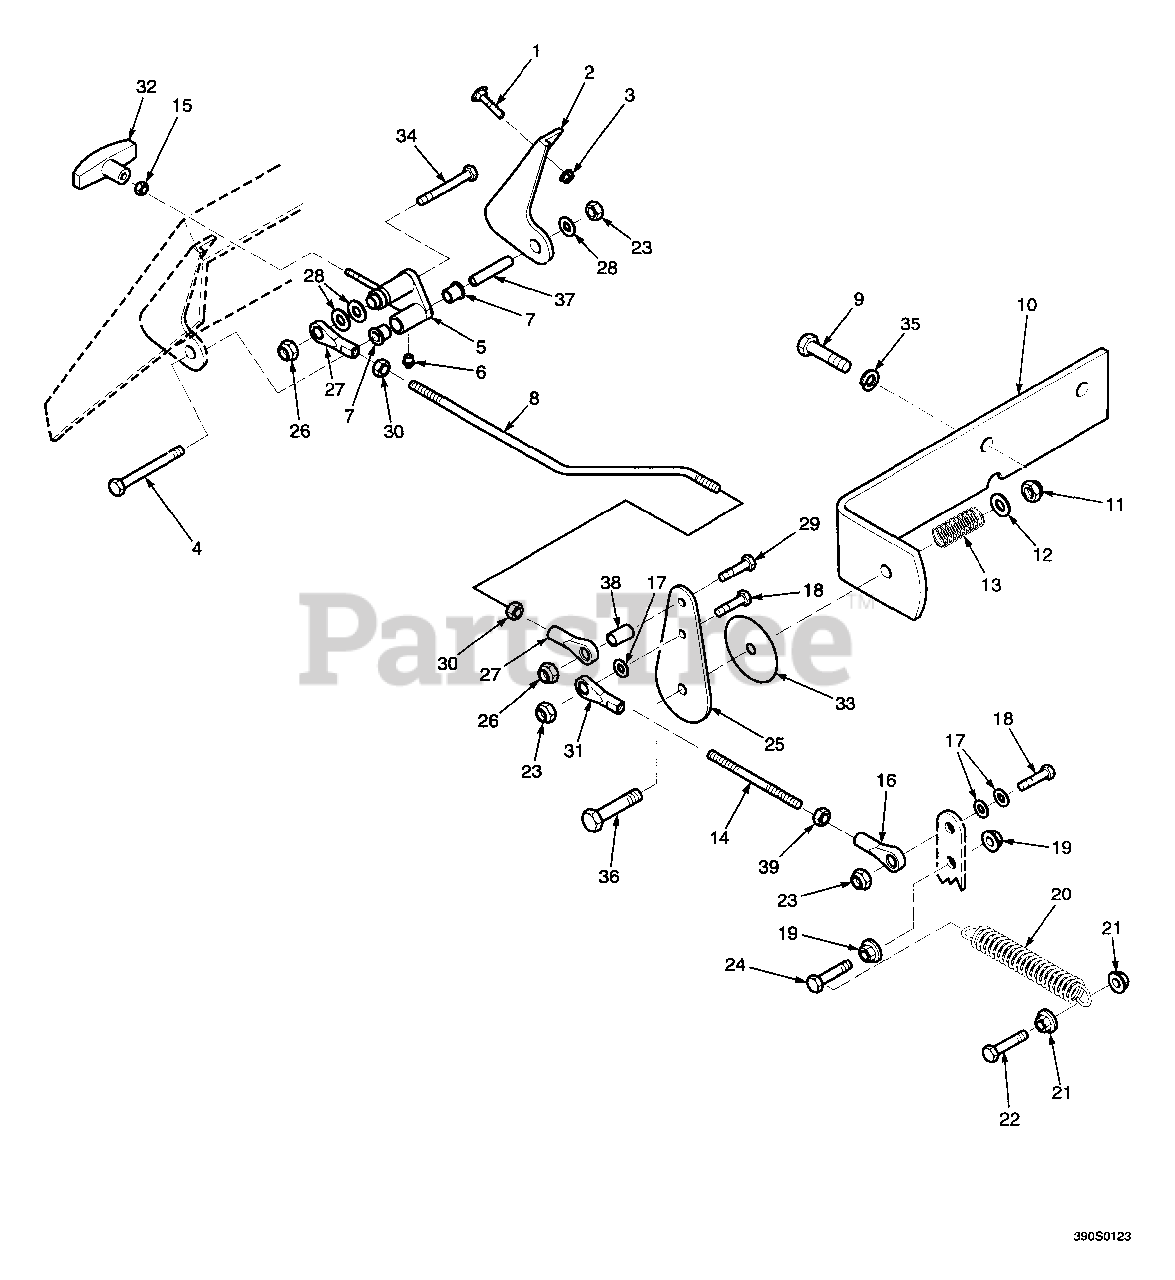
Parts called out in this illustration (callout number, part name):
1	Carriage Bolt, 1/4-20 x .75
2	Mounting Base, Throttle
3	Serr. Fl. Hex Nut, 1/4-20
4	Bolt, Hex Head, 5/16-18 x 2-3/4
5	Lever, Throttle
6	Grease Fitting
7	Bushing, Oilite - .5O I.D.
8	Rod, Throttle Control
9	Bolt, Hex Head, M10 - 1.25 x 30
10	Mounting Bracket, Throttle
11	Hex Locknut, Elastic Stop, 5/8-11
12	Flatwasher, 5/8
13	Spring, Friction Control
14	Stud, 5/16-24 x 4.50
15	Hex Nut, 5/16-18
16	Rod End, 5/16-24 RH Thread
17	Flatwasher, 5/16 (.344 x.688 x .065)
18	Bolt, Hex Head, 5/16-18 x 1-1/4
19	Serr. Fl. Hex Nut, 1/4-20
20	Spring, Throttle Control
21	Serr. Fl. Hex Nut, 5/16-18
22	Bolt, Hex Head, 5/16-18 x 2-1/4
23	Hex Locknut, Elastic Stop, 5/16-18
24	Bolt, Hex Head, 1/4-20 x 1-14
25	Lever, Throttle
26	Hex Locknut, Elastic Stop, 3/8-16
27	Ball Joint, 3/8-24 RH Thread
28	Flatwasher, 5/16
29	Bolt, Hex Head, 3/8-16 x 1-1/2
30	Hex Nut, 3/8-24
31	Rod End, 5/16-24 LH Thread
32	Knob, Shifter
33	Disc, Friction
34	Bolt, Hex Head, 3/8-16 x 3-3/4
35	Lockwasher, 7/16
36	Bolt, Hex Head, 5/8-11 X 3-1/2
37	Sleeve
38	Sleeve
39	Hex Nut, 5/16-24
